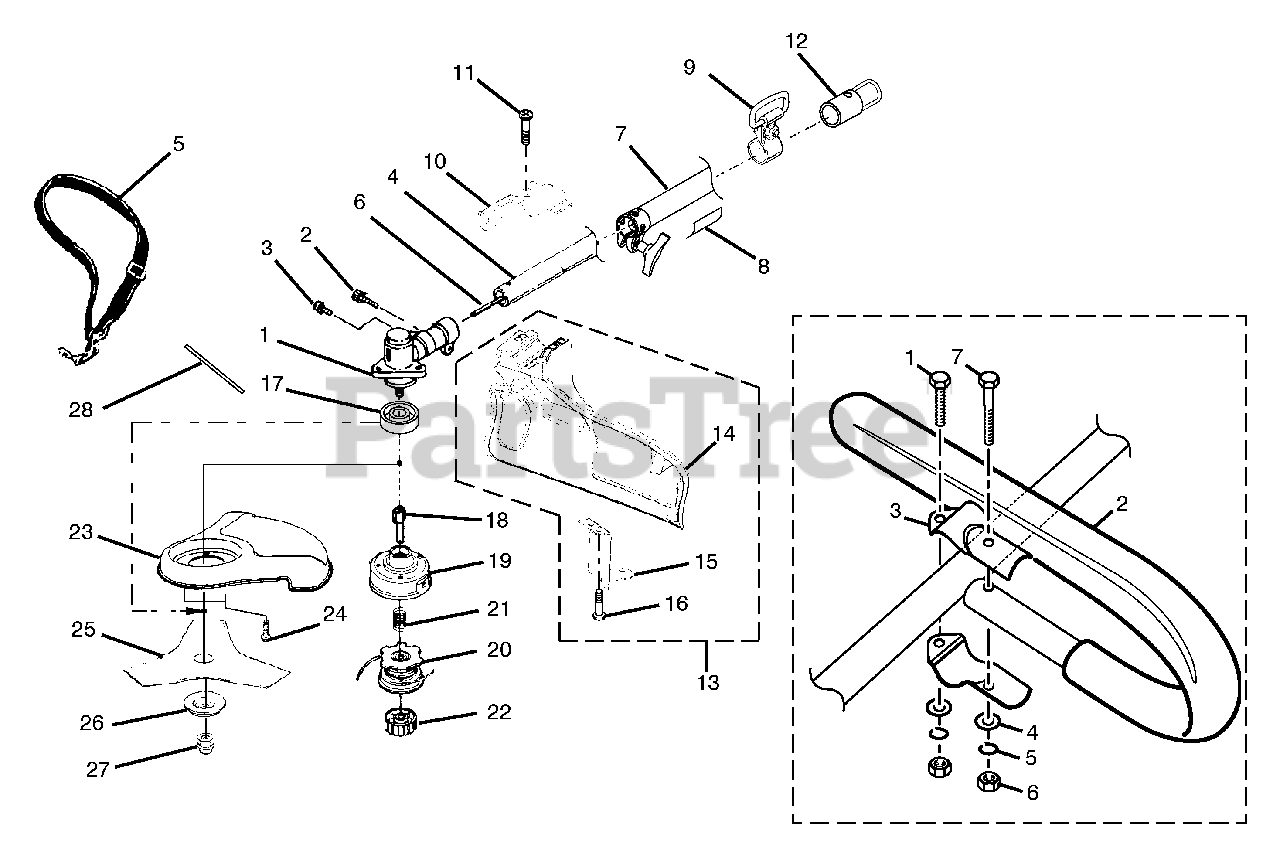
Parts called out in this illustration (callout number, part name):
1	GEAR HEAD
2	SCREW, CAP HD (1/4-20 x 125")
3	SCREW-HEX HD (10-24 x 625")
4	DRIVESHAFT HOUSING (Lower)
6	SHAFT-FLEXIBLE
7	DRIVESHAFT HOUSING (Upper)
8	DECAL, BOOM STARTING INST
9	HANGER-COMPLETE
10	CLAMP-GRASS SHIELD
11	SCREW-HEX HD (1/4-20 x 125")
12	END CAP
13	DEFLECTOR-GRASS ASSY
14	GRASS SHIELD
15	BLADE-CUT-OFF
16	SCREW-PAN HD (8-16 x 1/2")
17	WASHER-FLANGED
18	ADAPTER-STRINGHEAD
19	HOUSING AND EYELET (Dual Line)
20	SPOOL W/LINE (095 in)
21	COMPRESSION SPRING
22	SPOOL RETAINER (LH/THREAD)
23	BLADE GUARD
25	BLADE-TRI-ARC™
26	WASHER-CUPPED (Lower)
27	NUT-HEX (LH)
28	TOOL-HOLDING Pin
